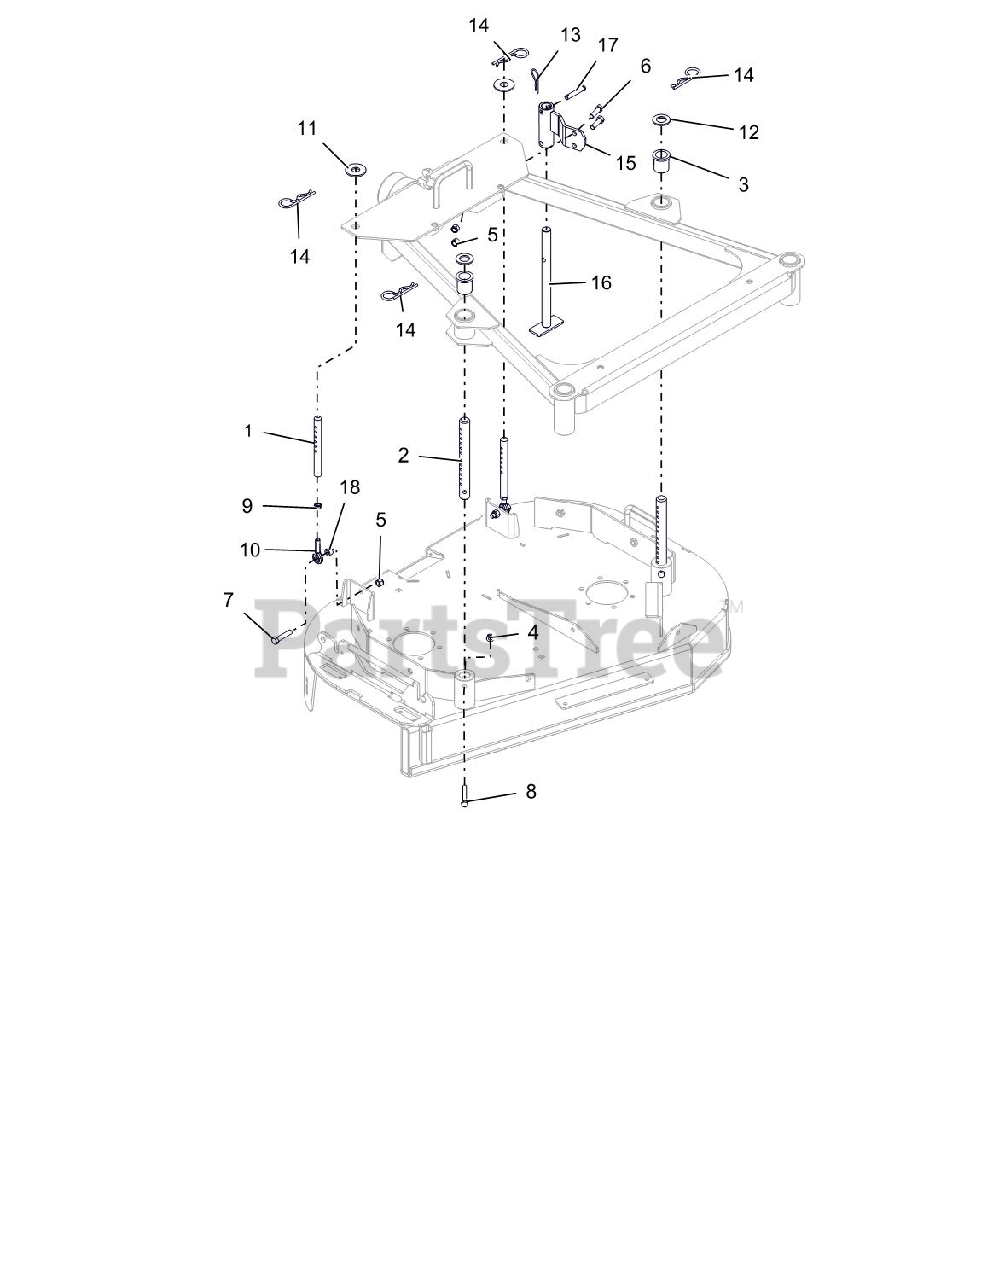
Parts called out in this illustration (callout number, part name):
1	PIN, REAR HOC
2	PIN, FRONT HOC
3	BSHG-FLG 1.00X1.25X1.50X1.50
4	NUT,SPNLK-FLG .312-18 ZC120
5	NUT,NYL .38-16 G5 ZCC
6	BLT, HEX .38-16X1.25 G5 ZCC
7	BLT, HEX .38-16X1.75 G5ZC120
8	BLT-HEX .31-18X2.50 G8ZC120
9	NUT-JAM .375-24 YWZC
10	ROD END, 3/8 RH
11	WSHR,FLT .688X1.75X.134 ZCC
12	WSHR-FL-STL .875X1.5X.119
13	PIN, HAIR-#7 .094X2.31 ZC120
14	PIN, HAIR-.17X.68X3.50 ZC120
15	BRKT, STAND (RED)
16	WLDT, STAND
17	PIN, CLEVIS
18	BSHG-SLV .377X.624X.370
